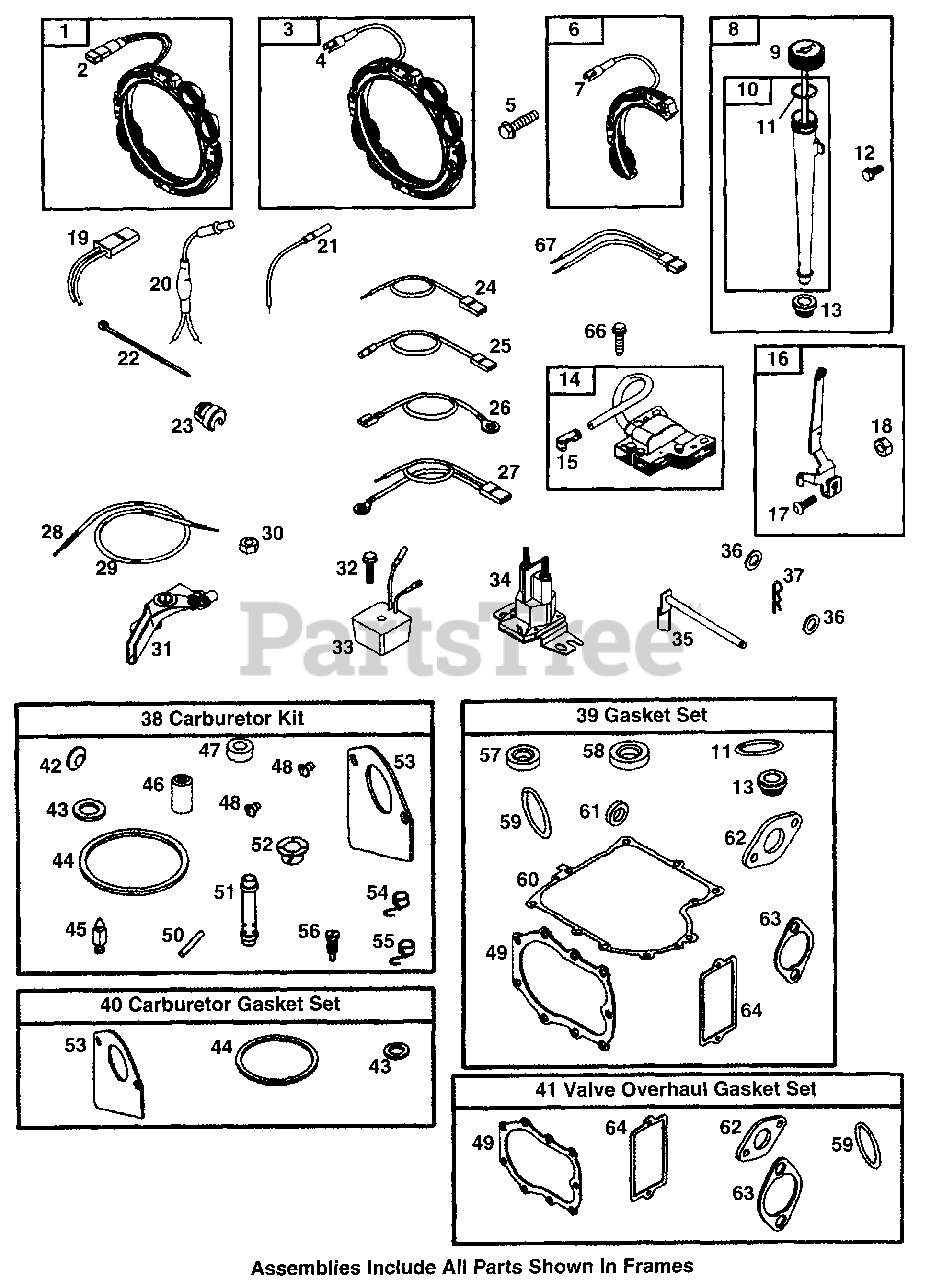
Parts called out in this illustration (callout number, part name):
1	Alternator/Stator (Dual Circuit)
2	Alternator Connector (Dual Circuit)
3	Alternator/Stator (Tri-Cir., 9A Regulated)
4	Alternator Connector (Tri Circuit, 9A)
5	Tapping Hex Screw
6	Alternator/Stator (DC Only)
7	Alternator Connector (Regulated 16A)
8	Oil Tube Assembly
10	Oil Fill Tube
11	Oil Fill Tube Seal
12	Hex Washer Head Screw
13	Tube Seal
14	Magneto-Armature
15	Cable Terminal
16	Governor Lever
18	Nut, 10-24
19	Alternator Harness (Dual Circuit)
20	Harness Assembly (Tri-Circuit)
21	Socket/Wire Assembly (DC Only)
24	Stop Wire
27	Stop Wire, 30"
28	Control Wire, 78"
29	Wire Casing, 48"
31	Control Lever
32	Hex Screw
33	Regulator Assembly, 9A
34	Starter Solenoid
35	Governor Crank
36	Plain Washer
37	Cotter Pin
38	Carburetor Kit
39	Gasket Set
40	Carburetor Gasket Set
41	Valve Overhaul Gasket Set
42	Welch Plug
43	Seal Washer
44	Float Bowl Gasket
45	Inlet Valve
46	Inlet Seat (Gravity Feed)
47	Throttle Shaft Seal
48	Round Washer Screw
49	Cylinder Head Gasket
50	Float Hinge Pin
51	Nozzle
52	Throttle Shaft Bushing
53	Carburetor Gasket
54	Spring and Seal Assy (Manual Choke)
55	Spring and Seal Assy (Choke-a-Matic)
57	Oil Seal
58	Oil Seal (for Crankcase Cover)
59	O-Ring Seal
60	Crankcase Gasket, .009"
62	Exhaust Pipe Gasket
63	Intake Gasket
64	Valve Cover Gasket
